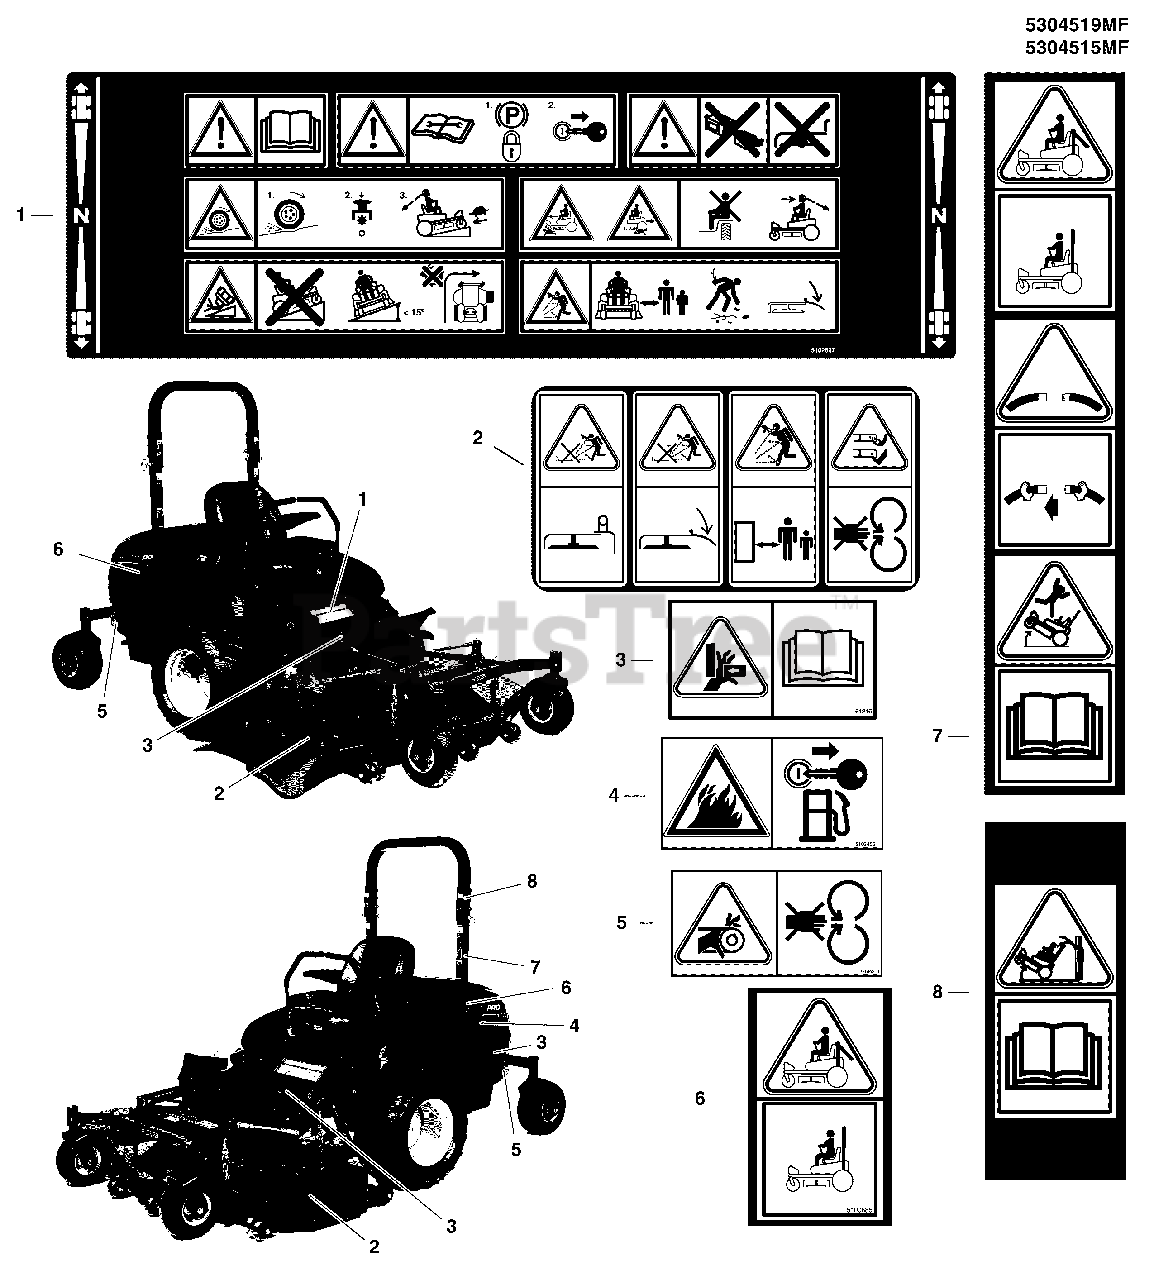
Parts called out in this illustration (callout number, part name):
1	DECAL, MAIN SAFETY, ANSI CE
2	DECAL, DISCHARGE SAFETY, EXPORT
3	DECAL, PINCH POINT, CE
4	DECAL, FIRE ANSI EXPORT
5	DECAL, CE DANGER
6	DECAL, WARNING, ROLL BAR, CE
7	DECAL, SAFETY, CE ROPS
8	DECAL, SAFETY, CE ROPS, OBS
